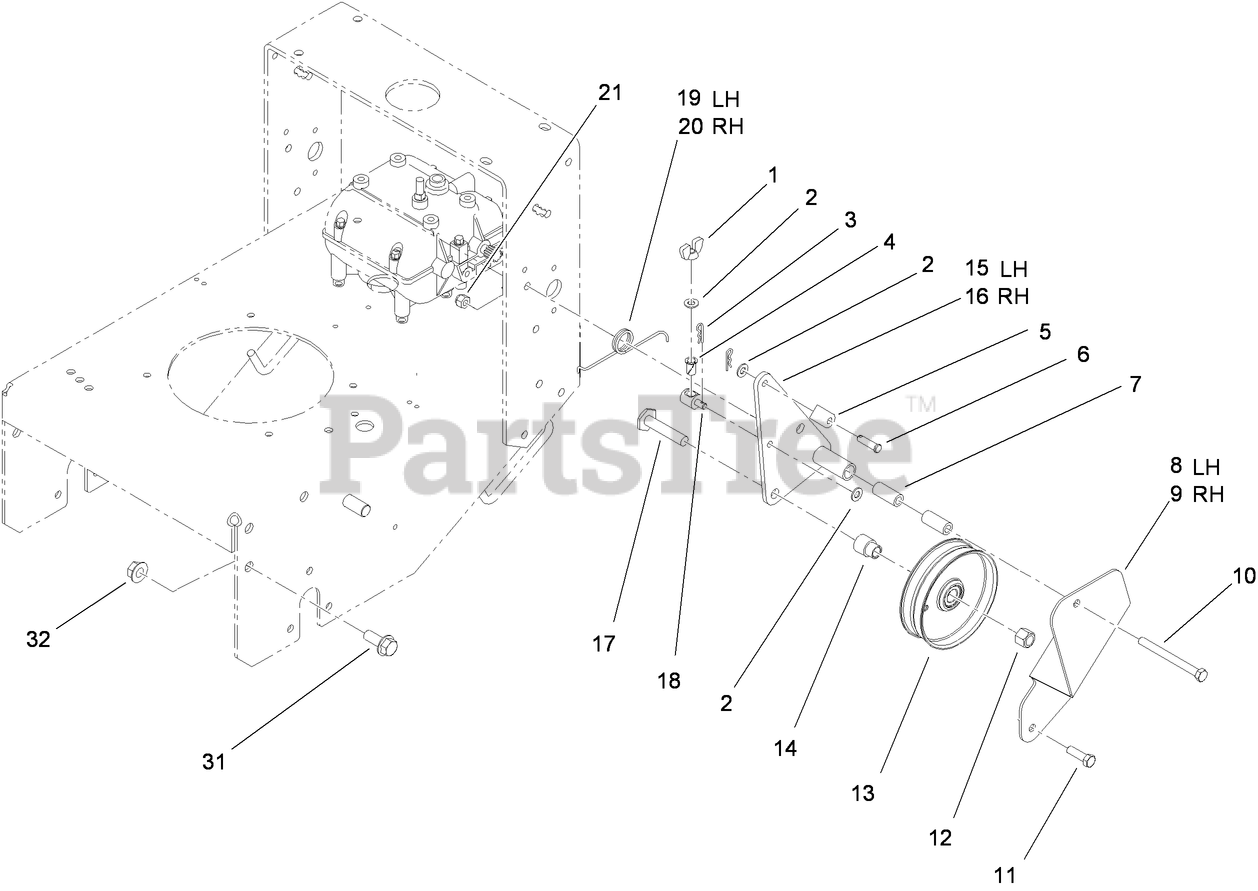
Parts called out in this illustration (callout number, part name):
1	NUT-WING
2	WASHER-PLAIN
3	PIN-COTTER
4	BUSHING-NYLON
5	FITTING-ROD
6	PIN-CLEVIS
7	SPACER-PIVOT, IDLER
8	SUPPORT-IDLER, LH
9	SUPPORT-IDLER, RH
10	SCREW-HH
11	SCREW-HH
12	NUT-LOCK, NI
13	PULLEY-IDLER
14	SPACER-PULLEY
15	ARM-IDLER, LH
16	ARM-IDLER, RH
17	SCREW-LEVELER
18	FITTING-ROD
19	SPRING-TORSION, LH
20	SPRING-TORSION, RH
21	NUT-LOCK, NI
31	SCREW-HHF
32	NUT-HF
